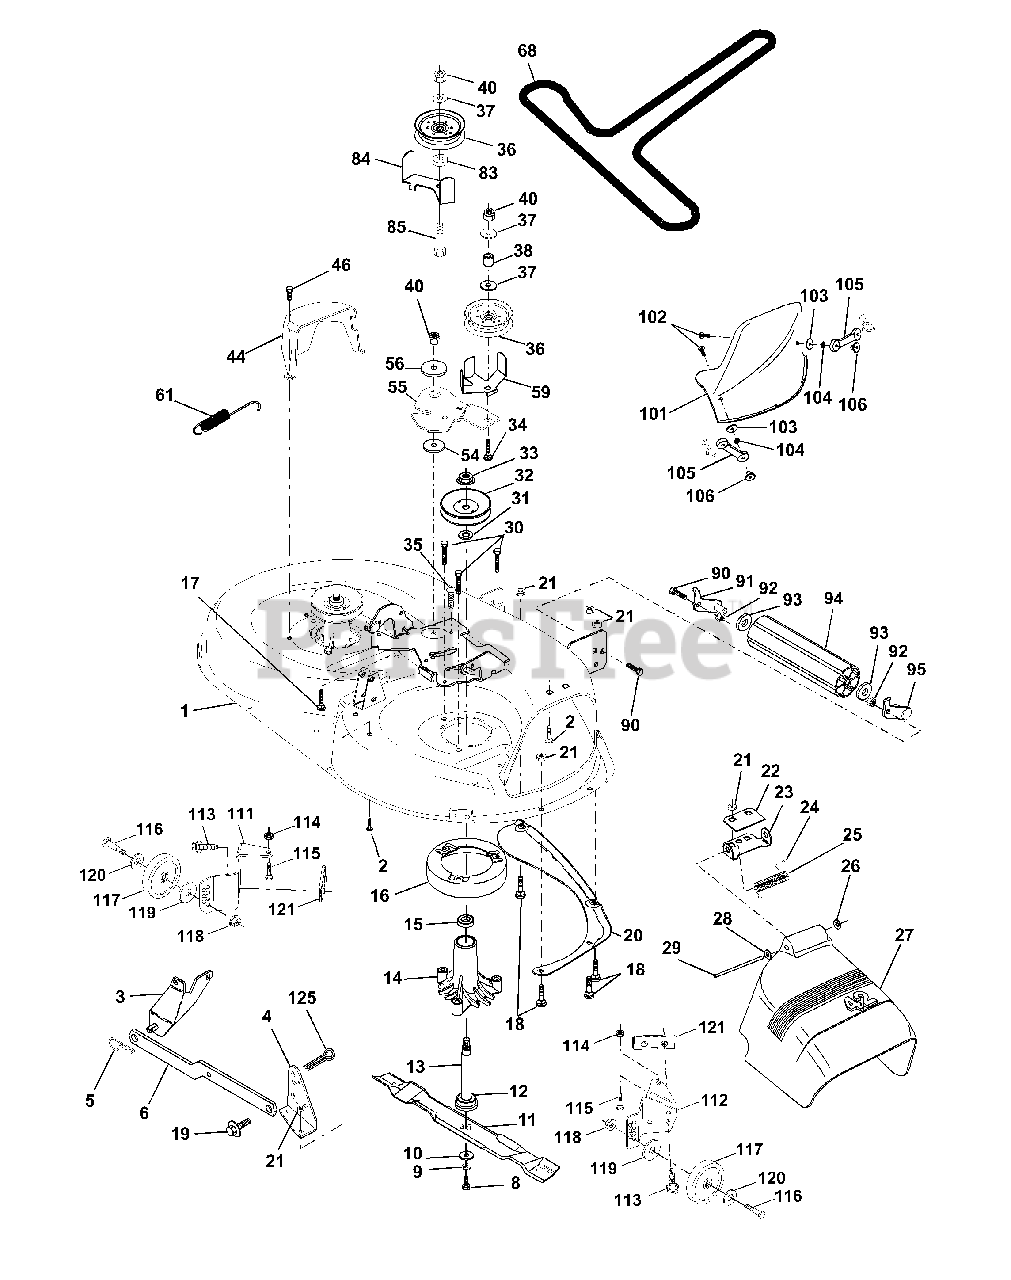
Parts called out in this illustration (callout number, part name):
1	Deck Asm MWR 42" 94 T-Path
2	Bolt Rdhd Sqnk 5/16-18unc X3/4
3	Bracket Asm Fr Sway Bar 38/42
4	Bracket Asm Deck 42"sway Bar
5	Retainer Spring
6	Arm Suspension Rear
7	Locknut-hex W/ins 5/16-18unc P
8	Bolt 3/8-24x1 25 Gr8 Patched
9	Washer Lock Hvy 3/8 Unplated
10	Washer Hard Blade Mower Vented
11	Blade Mower Mulching 42"
12	Bearing Ball #6204 (Mandrel)
13	Shaft Asm W/lower Bearing
14	Housing Mandrel Vented(machd)
15	Bearing Ball Mandrel
16	Stripper Mower Round
17	Bolt Rdhd Sqnk 3/8-16 X 2-1/4
18	Bolt Carr 5/16-18 X 5/8
19	Bolt Shoulder
20	Baffle Vortex 42
21	Nut Crownlock 5/16-18
22	Stiffener Bracket 42" deck
23	Bracket Deflector Mower 42"
24	Cap Sleeve 80x 112 Blk Mower
25	Spring Torsion Deflector 2 52
26	Nut Push Phos & Oil
27	Shield Deflector Mower 42" Blk
28	Washer 11/32 X 5/8 X 16 Ga
29	Rod Hinge 42"6 75 Wlg
30	Screw Thdrol Hex Hd Zinc Mwr.
31	Washer Spacer Mower Vented
32	Pulley Mandrel 42"
33	Nut 9/16top Lock Flng Cntr
34	Bolt Rdhd 3/8-16uncx2-3/4 Gr5
35	Fastner Christmas Tree
36	Pulley Idler Flat 3 060
37	Washer 13/32 X 13/16 X 16 Ga
38	Spacer Spring Stop Idler
40	Nut Crownlock 3/8-16 UNC
44	Guard Mandrel LH Black
46	Screw Thdrol 1/4-20x5/8
54	Washer Hardened
55	Arm Idler 42"mower LT/YT
56	Spacer Retainer Pm Mower
59	Guard, Belt
61	Spring Ext. Elect
68	V-Belt Mower
83	Washer Sintered
84	Keeper Belt Idler Fixed
85	Bolt RDHD SQNK 3/8-16 x 2-1/4 Gr. 5
90	Bolt Fin Hex 3/8-16unc X 1
91	Bracket Asm Noseroller LH
92	Nut Crownlock 3/8-16 Unc
93	Washer 17/32 X 7/8 X 16 Ga
94	Roller Nose 38 & 42
95	Bracket Asm Noseroller RH
101	Cover Mulching 42" Blk
102	Screw
103	Washer Lock #10
104	Washer #10
105	Latch Asm Bagger
106	Nut Weld .327/.304 #10-24
111	Bracket Wheel Guage Lh 42" Deck
112	Bracket Guage Wheel Rh 42" Deck
113	Screw Thdrol 5/16-18 x 3/4 TYT
114	Nut Keps 5/16 - 18 UNC
115	Bolt Carriage 5/16 - Unc x 1/2
116	Bolt Shld "A" 2.41 "B" 1.66
117	Wheel Guage blk. 4.93
118	Nut Centerlock 3/8 - 16 UNC
119	Washer 3/8 x 7/8 x 14 Ga.
120	Washer 17/32 x 15/16 x 12 Ga.
125	Pin Cotter 1/4 x 1 Plated
